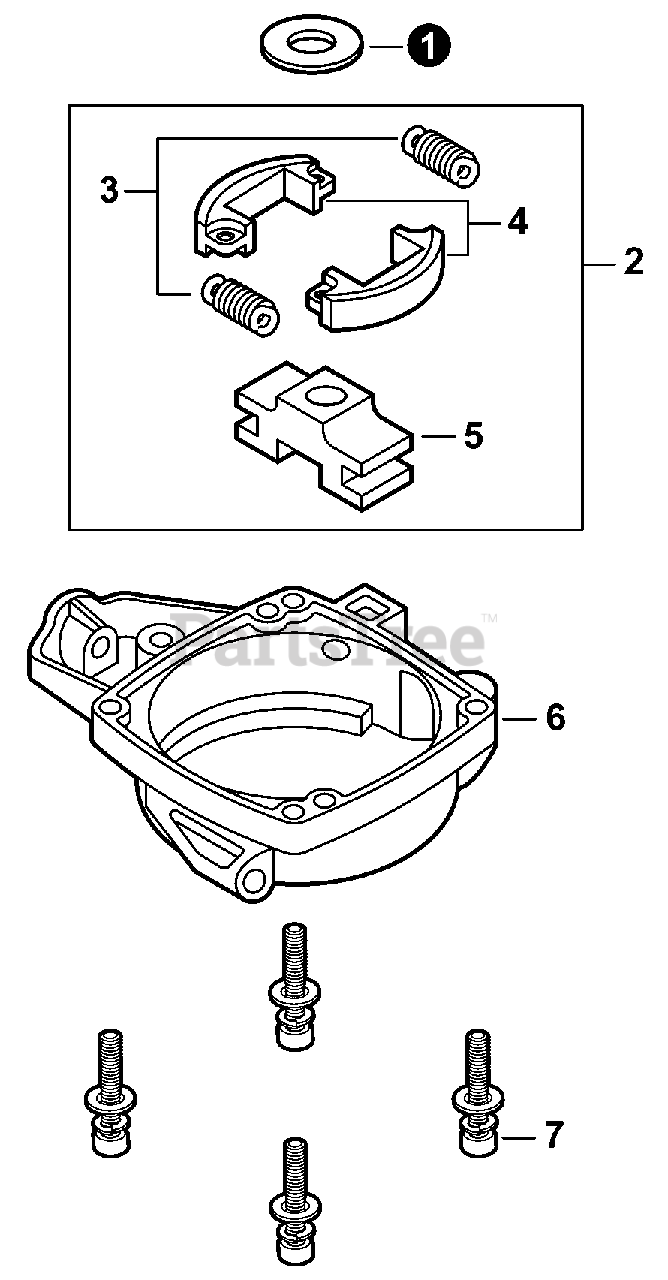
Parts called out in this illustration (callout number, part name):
1	WASHER 8
2	CLUTCH ASSY
3	SPRING, CLUTCH
4	SHOE, CLUTCH
5	HUB, CLUTCH
6	CASE, CLUTCH
7	BOLT 4×16
